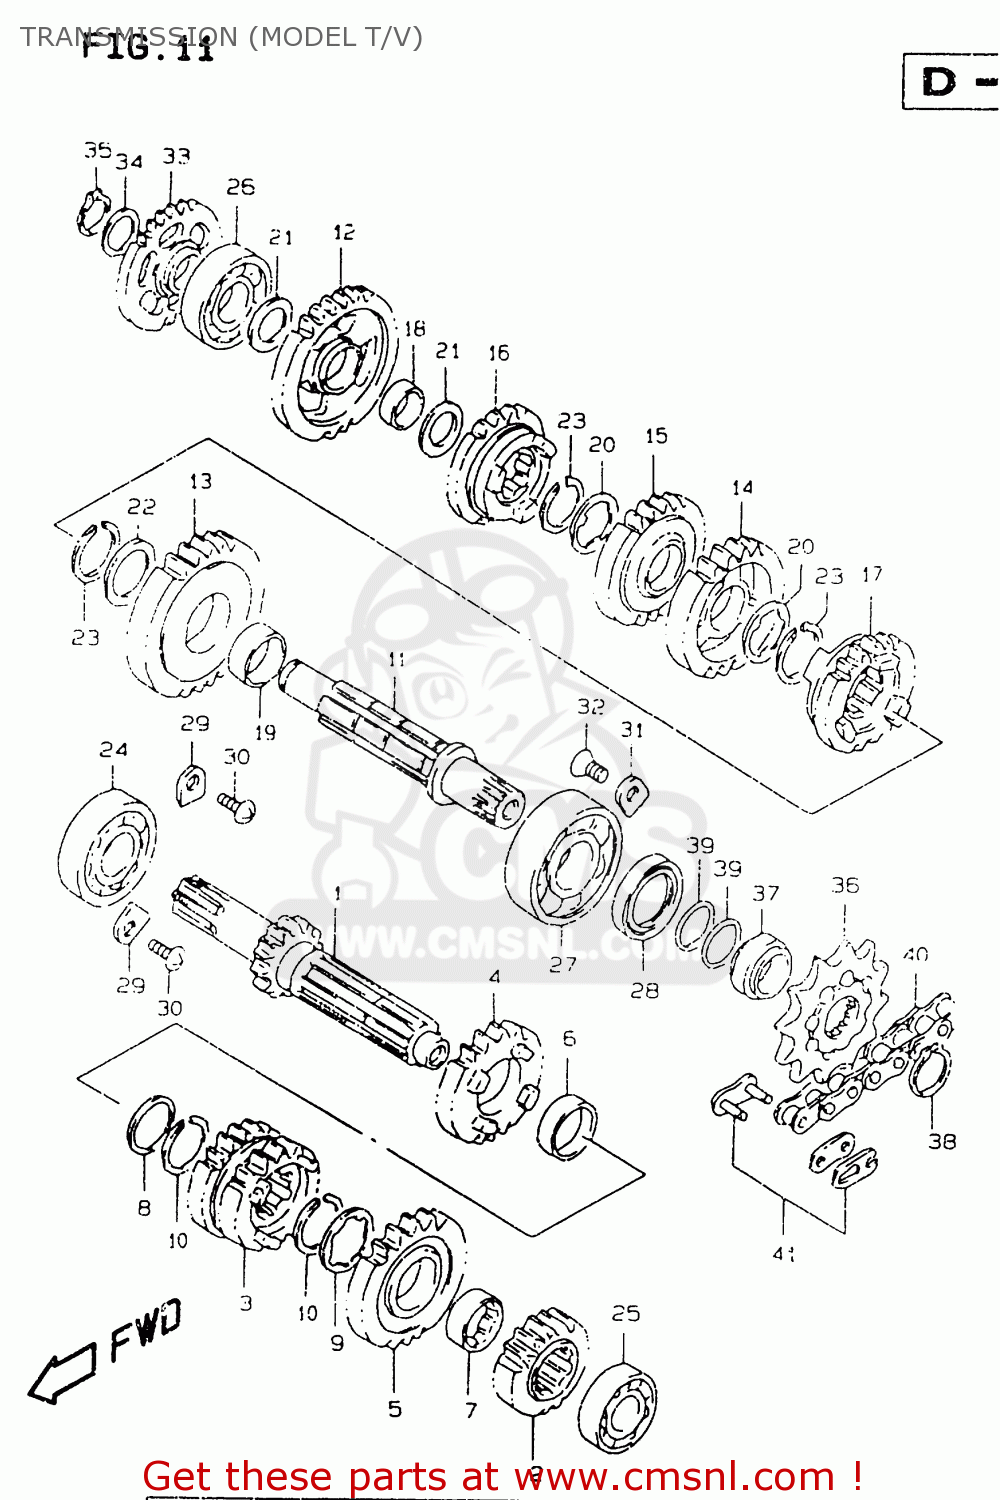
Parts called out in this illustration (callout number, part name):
1	SHAFT,COUNTER(NT:14)
2	GEAR,2ND DRIVE(NT:16)
3	GEAR,THIRD & FOURTH DRIVE,N
4	GEAR,FIFTH DRIVE (NT:19)
5	GEAR,SIXTH DRIVE (NT:20)
6	BUSH(22X26X9)
7	BUSH,6TH DRIVE GEAR
8	SHIM
9	WASHER,LOCK
10	CIRCLIP
11	SHAFT,DRIVE
12	GEAR,1ST DRIVEN(NT:30)
13	GEAR,2ND DRIVEN(NT:28)
14	GEAR,3RD DRIVEN(NT:26)
15	GEAR,4TH DRIVEN(NT:24)
16	GEAR,5TH DRIVEN(NT:20)
17	GEAR,6TH DRIVEN(NT:19)
18	BUSH(17X20X9)
19	BUSH(22X26X9)
20	WASHER
21	WASHER,THRUST
22	WASHER,THRUST
23	CIRCLIP
24	BEARING(20X47X12)
25	BEARING
26	BEARING(17X40X9.5)
27	BEARING(20X52X12.5)
28	SEAL,OIL(28X38X6)
29	RETAINER
30	SCREW
31	RETAINER,COUNTER BEARING,R
32	SCREW
33	GEAR,KICK STARTER IDLE
34	SHIM
35	CIRCLIP,17MM
36	SPROCKET,ENGINE
37	SPACER,ENGINE SPROCKET
38	CIRCLIP
39	O RING(D:1.9,ID:19.8)
40	CHAIN ASSEMBLY DID520DM.11
41	JOINT SET,CHAIN
